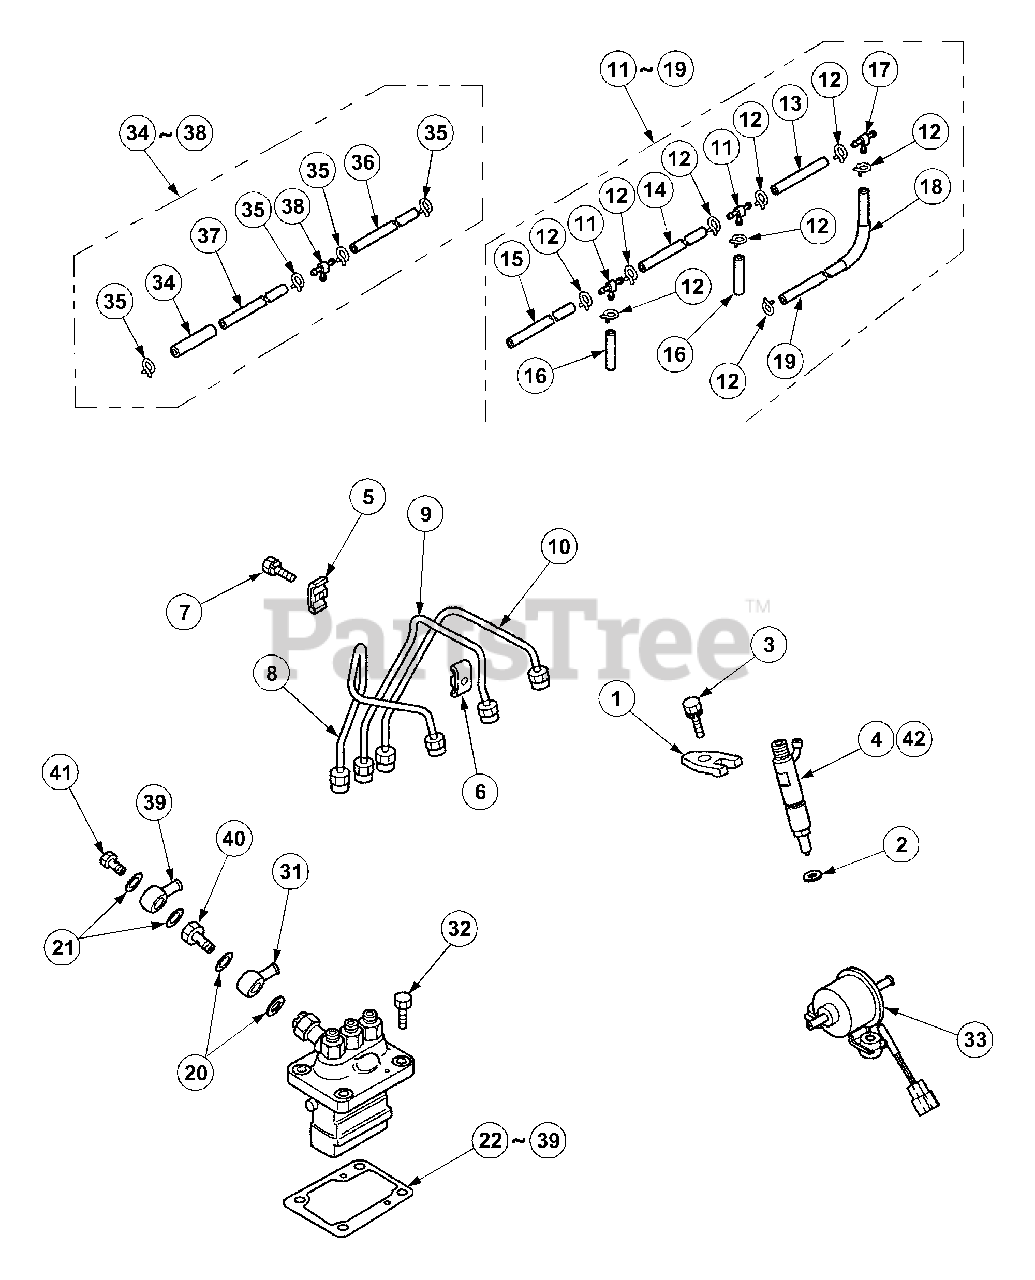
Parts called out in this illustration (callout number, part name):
2	Gasket,Nozzle
3	Bolt,w/Washer
7	Bolt,w/Washer
13	Pipe,Rubber
14	Pipe,Rubber
15	Pipe,Rubber
16	Pipe,Rubber
20	Washer,Seal
21	Washer,Sealing
22	Shim, t=0.2
23	Shim, t=0.3
24	Shim, t=0.4
25	Shim, t=0.5
26	Shim, t=0.6
27	Shim, t=0.7
28	Shim, t=0.8
29	Shim, t=0.9
30	Shim, t=1.0
32	Bolt
33	Pump Assy,Fuel
36	Pipe,Rubber
37	Pipe,Rubber
41	Valve Assy,Check
42	Nozzle Assy
